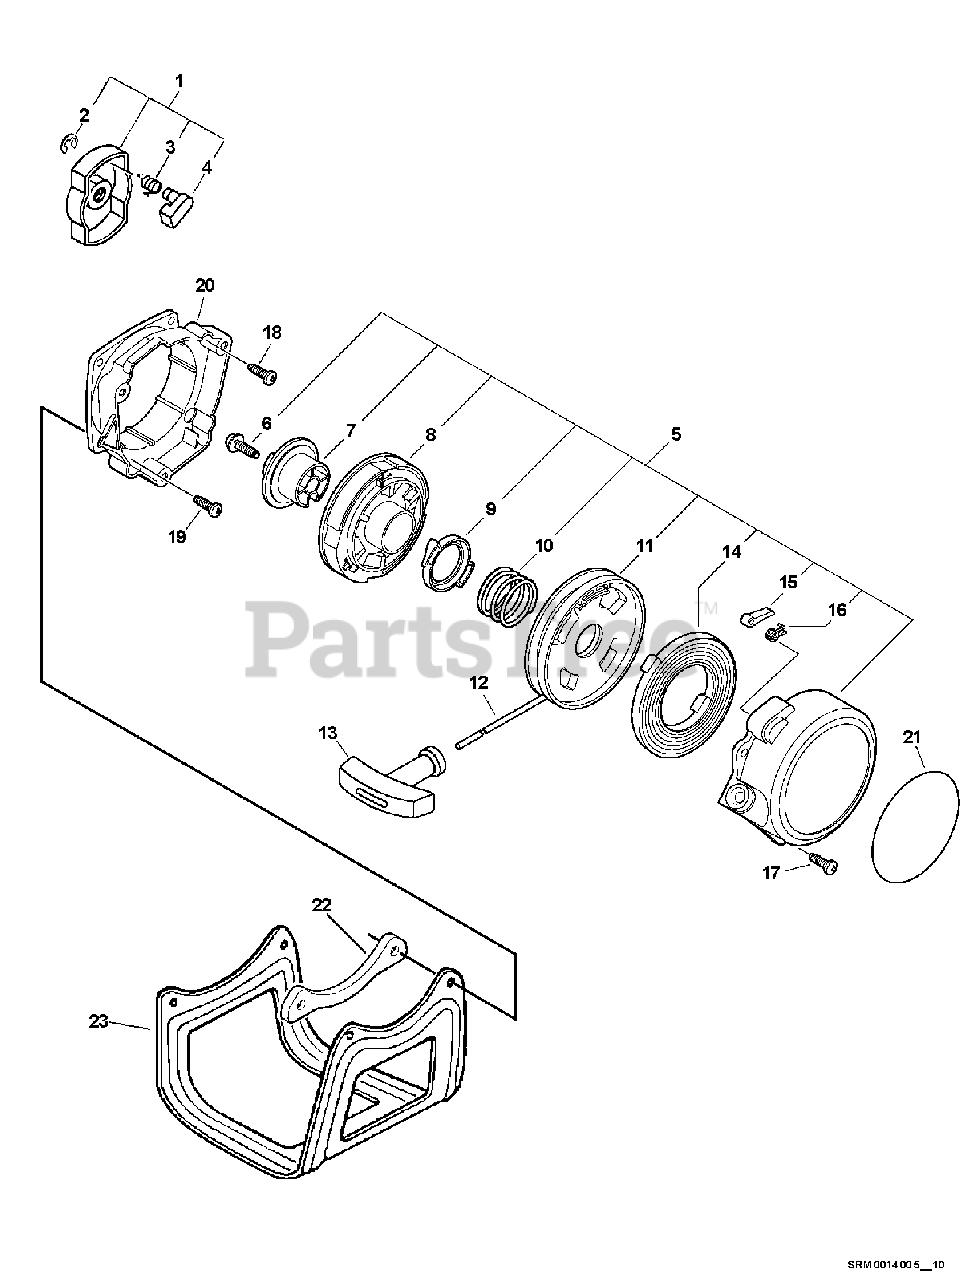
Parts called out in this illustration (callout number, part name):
1	STARTER PAWL ASSY
2	PAWL, STARTER
3	SPRING, RETURN
4	RING, RETAINING - 4
5	STARTER ASSY
7	PLATE, CAM
8	SPRING ASSY
10	SPRING, RETURN
11	REEL, ROPE
12	ROPE, STARTER - 3X800
13	GRIP, STARTER
14	SPRING, REWIND
15	PAWL, STARTER
16	SPRING, PAWL RETURN
17	SCREW - 5X20 -- TAPPING
18	SCREW - 4X16
19	SCREW - 4X20
21	LABEL - ECHO -- i
23	GUARD, FUEL TANK
